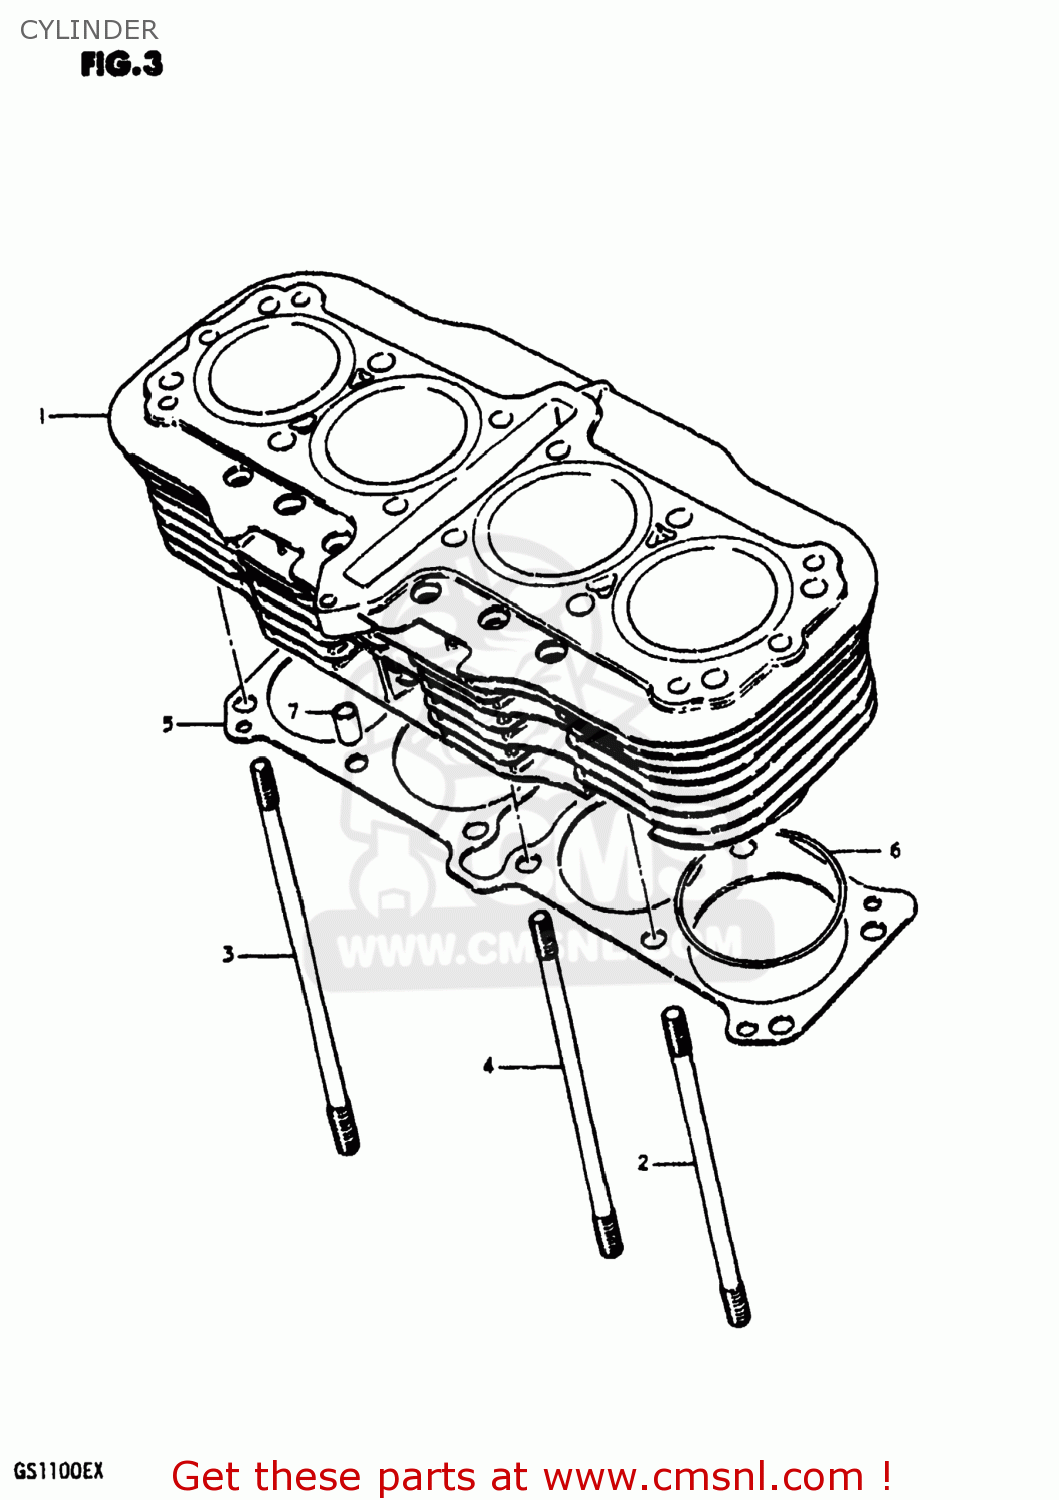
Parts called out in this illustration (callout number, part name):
1	CYLINDER
2	BOLT,STUD
3	STUD
4	BOLT,STUD
5	GASKET,CYLINDER (MCA)
6	O RING(D:2,ID:74)
7	PIN
